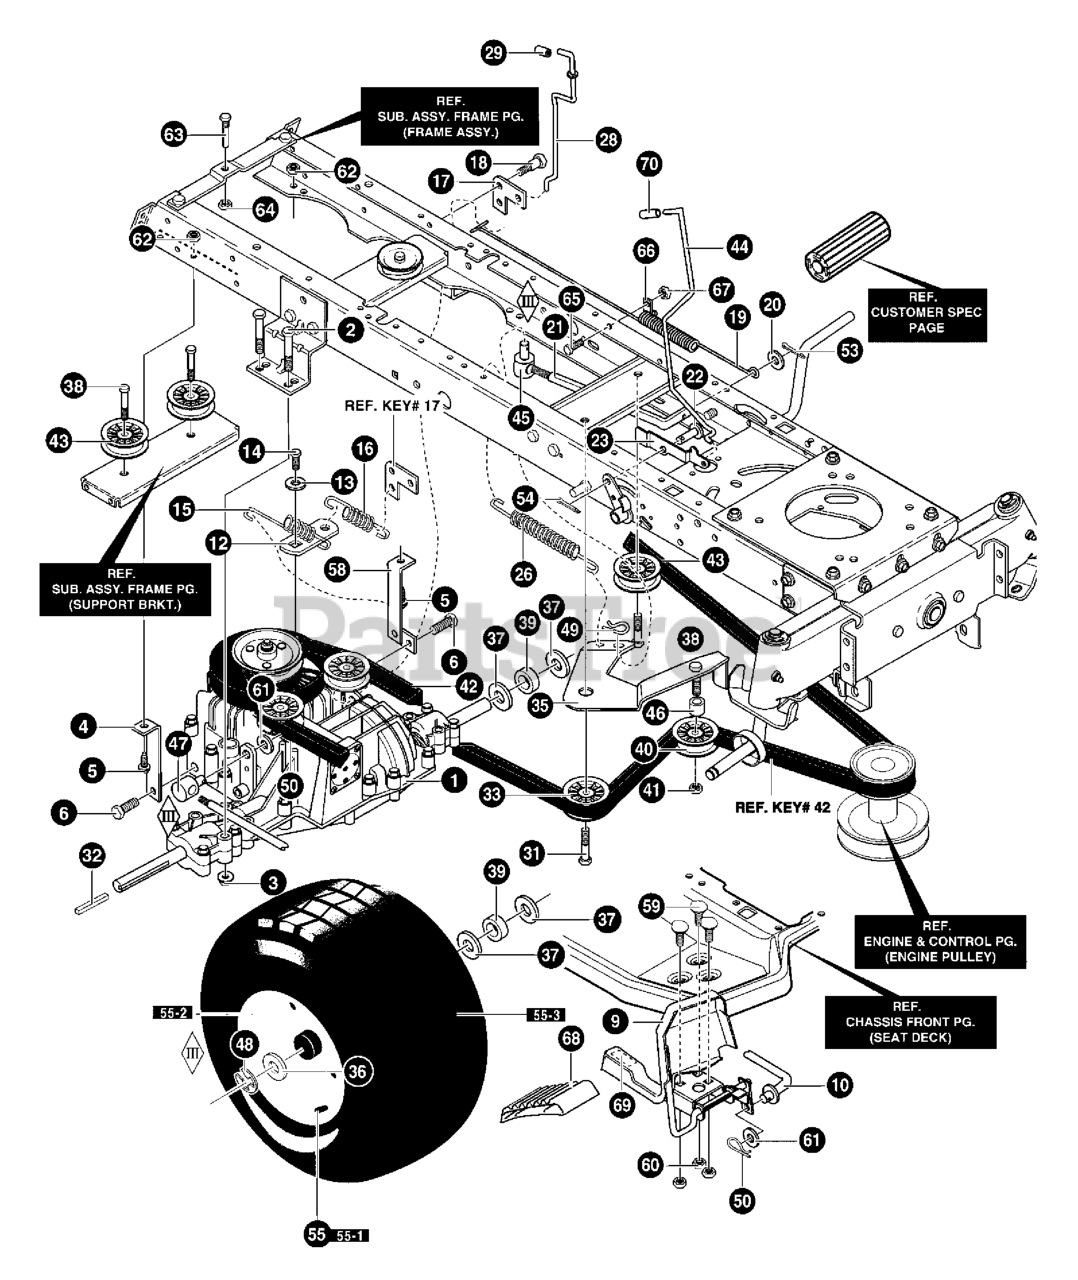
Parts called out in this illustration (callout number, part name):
1	Transaxle, Peerless Hydro **
2	SCREW, 5/16-18 x 2.50
3	NUT, 5/16-18 WDFLLK
4	STABILIZER BRACKET
5	SCREW, 5/16-18 x 1.00
6	SCREW, 5/16-18 x 0.75 WAHHTAP
9	PEDAL ASSY. HYDRO
10	ROD, FOOT CONTROL
12	BRKT, SHIFT
13	WASHER, TRANSAXLE
14	SCREW, 1/4-28X.750
15	SPRING - TRANSAXLE
16	SPRING, 3/8ODX2.18X.055
17	BRACKET, DISCONNECT LEVER
18	BOLT, HHSH 5/16-18
19	SPRING, BRAKE
20	WASHER, FLAT .328X1.06X.062
21	ROD, CLUTCH
22	PIN, CLEVIS .375DX.81LG
23	ZINC LATCH, PARK BRAKE
26	SPRING, TENSION .096X.80ODX5.00LG
28	ROD, DISCONNECT CONTROL
29	GRIP, HYDRO DISCONNECT
31	SCREW, 3/8-16 x 1.25
32	KEY, SQUARE .187SQX2.25LG
33	PULLEY, IDLER V4L 3.00X.710
35	ASSY., IDLER ARM TRACTION
36	WASHER, FLAT .765 x 1.81 x .059
37	WASHER, FLAT .755ID
38	SCREW, 3/8-16 x 1.25
39	SPACER .87X1.78
40	PULLEY, IDLER 2.75 DIA
41	NUT, 3/8-16 HWDFLLK MACK
42	BELT, V4L 112.75
43	PULLEY, IDLER V4L 3.00X.710
44	PARK BRAKE CONTROL ROD
45	SPACER 1/2 TO 17MM
46	ROD, SHIFT
47	ADJUST NUT 1/2-13
48	E-RING .574IDX.050/.750SH
49	PIN, HAIR .072X1.13LG
50	PIN, HAIR
53	COTTER PIN
54	COTTER PIN
55	TIRE & RIM ASSY
55-1	VALVE STEM
55-3	TIRE 20X8X8
58	ASM., BRACKET STABILIZER
59	BOLT, 5/16-18X.75 CARR.
60	NUT, 5/16-18 HEXWDFLLK
61	WASHER, FLAT .515X.88X.0
62	NUT, 5/16-18X.75 WAHHTAP
63	SCREW GUIDE
64	NUT, 5/16-18 HEXWDFLLK
65	SCREW, 1/4-20X.50
66	WIRE RETAINER
67	NUT, 1/4-20 WDFLWHIZ-LK
68	PEDAL, PAD SANDPAPER
69	PAD, TOE SANDPAPER
70	CAP, DUMP VALVE ROD
